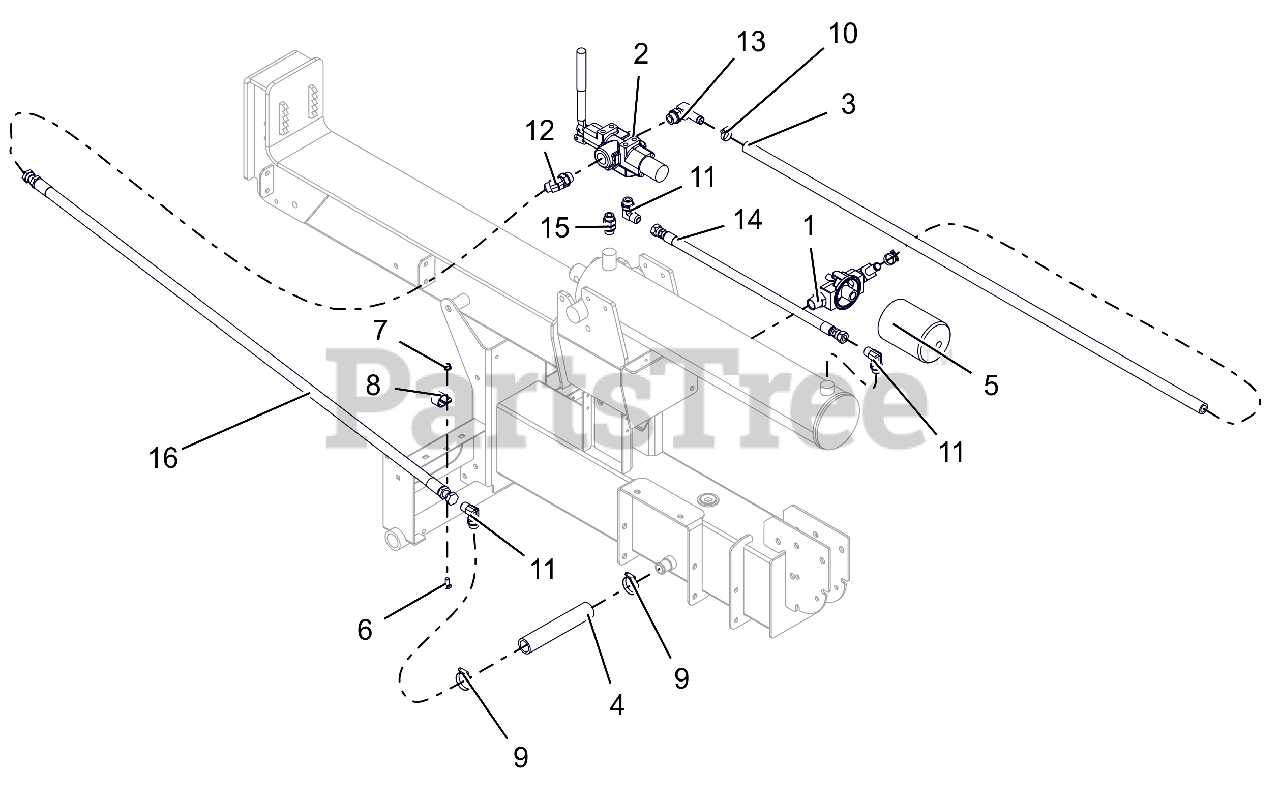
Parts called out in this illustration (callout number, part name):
1	ASM, FILTER HEAD
2	VALVE CONTROL-SPLITTER
3	HOSE,HYD RETURN 10LOLA X 53"
4	HOSE, HYD - SUCTION 7.375"
5	FILTER,HYDRAULIC OIL-NO BYPASS
6	@BLT-RDHDSQNK .31-18X.75 G5YZ
7	@NUT-LK-TOP-FLG .31-18 YWZC
8	CLAMP, COUSHIONED STEEL REV
9	CLAMP-HOSE 1.50X.81X1.42
10	CLAMP,.88 DIA. HOSE
11	FTG,HYD 6801-8-8
12	FTG,HYD 6802-8-10
13	FTG,HYD 4601-10-10
14	HOSE, HYD - 22"
15	FTG, HYD - STR 08MAORB-08MORB
16	HOSE, HYD - 58"
